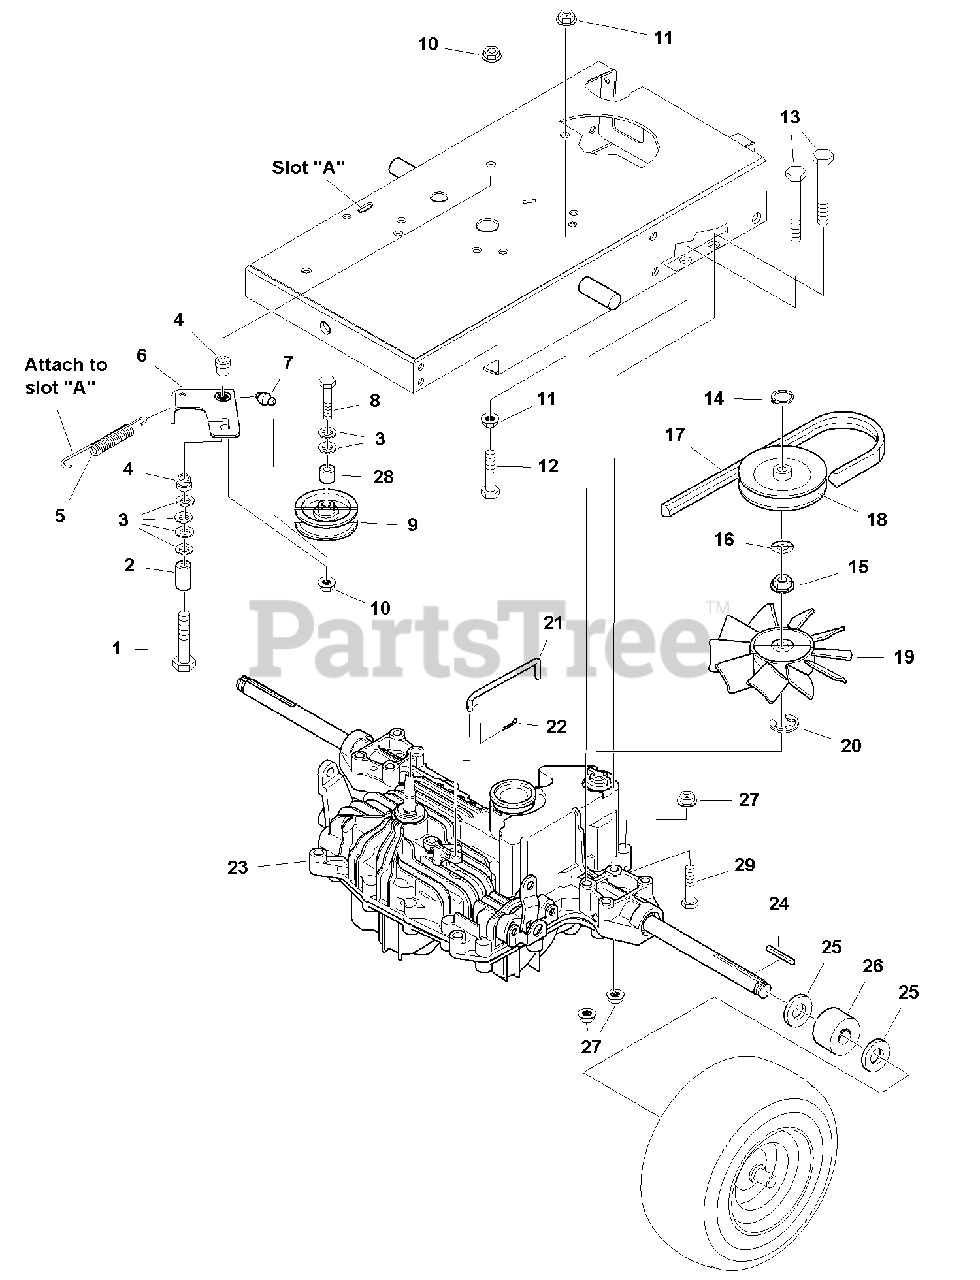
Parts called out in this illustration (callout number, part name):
1	CAPSCREW, Hex Head, 3/8-16 x 2, Black
3	WASHER, 3/8, Black
5	SPRING, Extension, 7-3/4" Long
6	ARM ASSEMBLY
7	FITTING, Lube
8	CAPSCREW, Hex Head, 3/8-16 x 1-1/2, Black
9	PULLEY, Idler, 3-1/4
10	NUT, Hex Flange Lock, 3/8-16, Black
11	NUT, Hex Flange Lock, 5/16-18, Black
12	CAPSCREW, Hex Head 5/16-18 x 2 G5
13	CAPSCREW, Hex Head, 5/16-18 x 2-1/2, Black
15	SPLINE COLAR
19	FAN
20	"E" RING
21	ROD, Hydro Bypass
22	PIN, Cotter
23	TRANSMISSION ASSEMBLY, Foot Control, K46Q
24	KEY, Parallel
25	WASHER, 3/4
27	NUT, Hex Flange Lock, 5/16-18
29	CAPSCREW, Hex Head, 5/16-18 x 1-3/4
